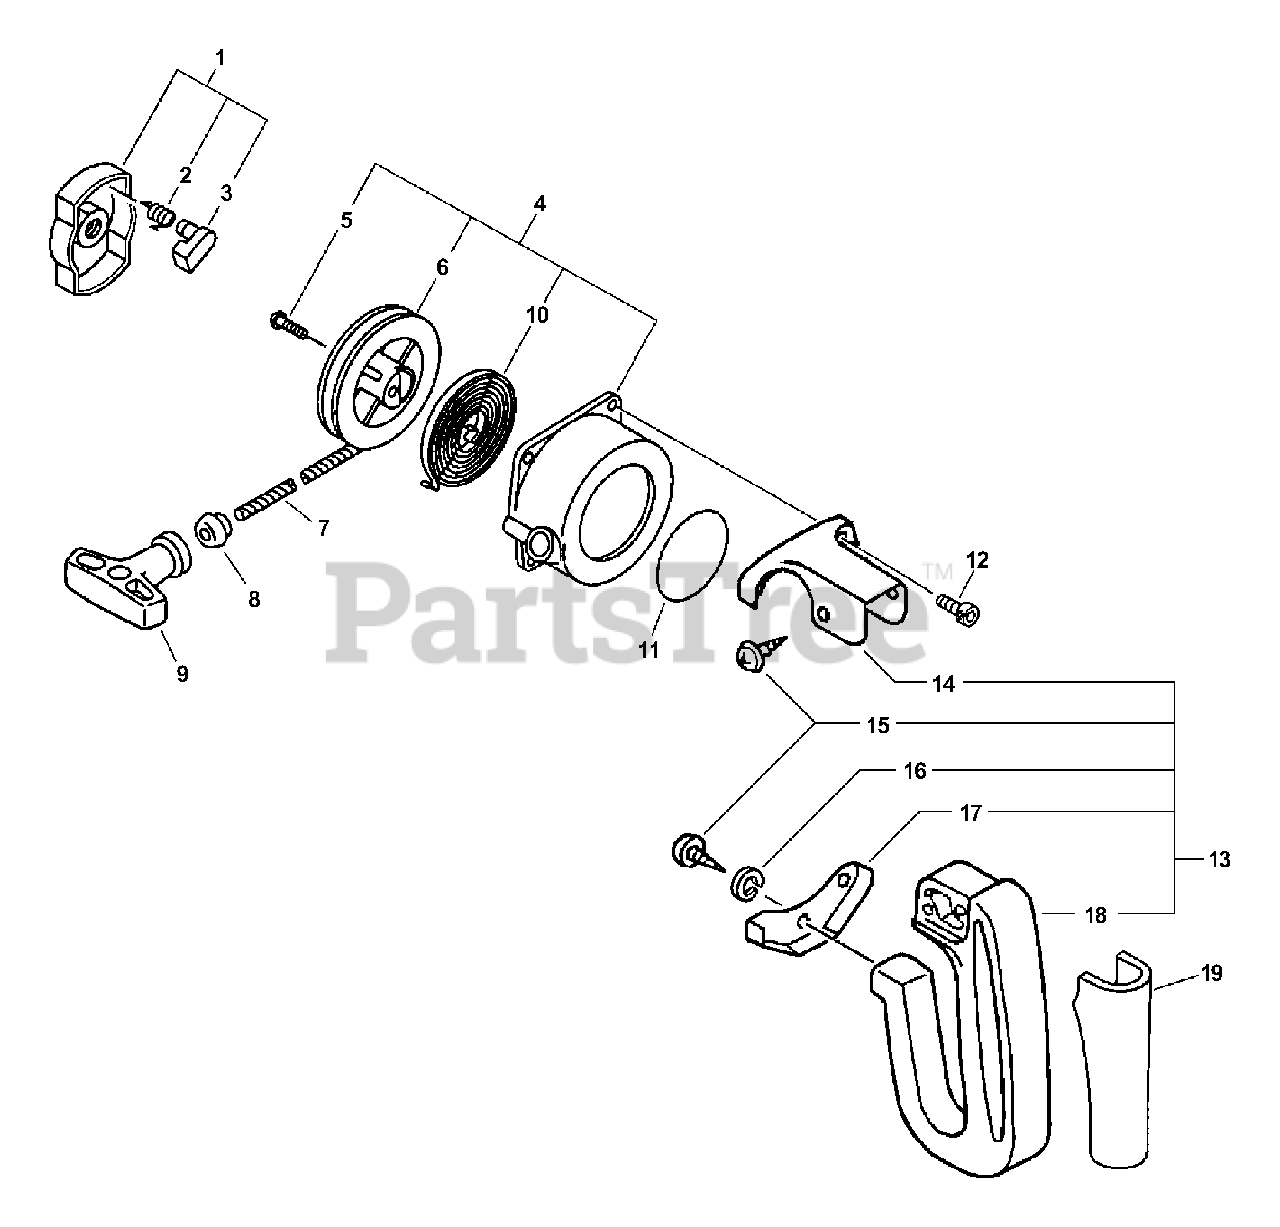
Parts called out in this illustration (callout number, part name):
1	STARTER PAWL ASSY
2	SPRING, RETURN
3	PAWL, STARTER - BLACK
4	STARTER ASSY
6	REEL, ROPE
7	ROPE, STARTER - 3X1000
8	GUIDE, ROPE
9	GRIP, STARTER
10	SPRING, REWIND
11	SCREW - 4X16
12	LABEL - ECHO
13	HANDLE ASSY - REAR
14	SCREW - 5X16 -- TAPPING
15	BRACKET, HANDLE - UPPER
16	LOCKWASHER - 5
17	BRACKET, HANDLE - LOWER
18	HANDLE - REAR
19	GRIP, HANDLE
